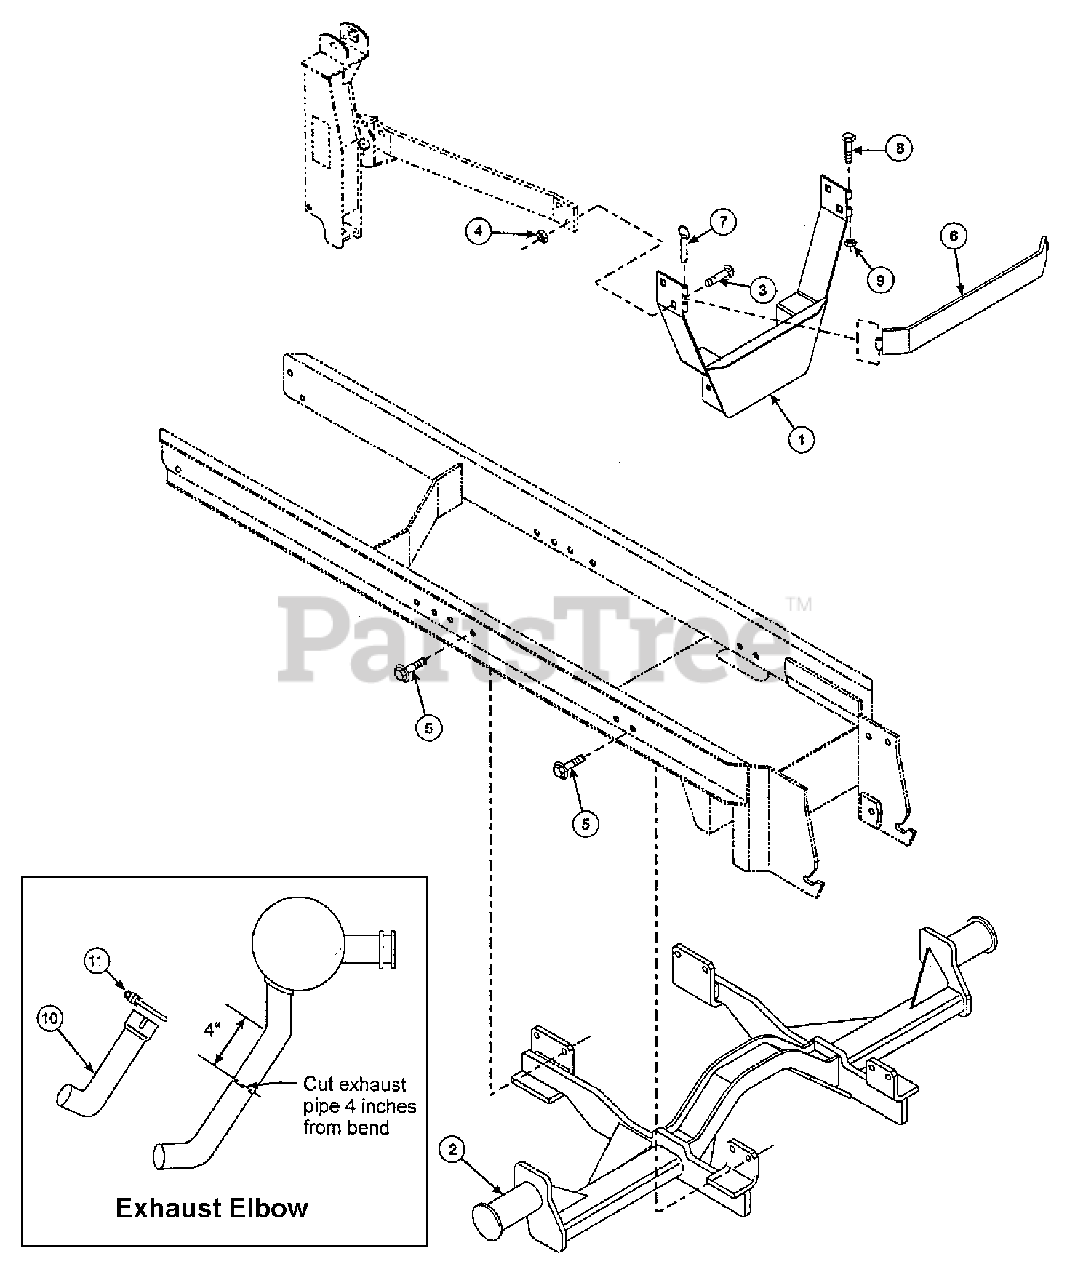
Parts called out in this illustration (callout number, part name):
1	BRACKET, Front Mounting
2	BRACKET, Mid Mounting
3	CARRIAGE BOLT, 1/2-13 x 1-1/2
4	LOCKNUT, 1/2-13
5	CAPSCREW, Hex Flange Head, Whiz Lock, 3/8-16 x 3/4
7	PIN, Locking, 3/8-16 x 4
8	CAPSCREW, Hex Head, 3/8-16 x 4
9	LOCKNUT, Hex, 3/8-16
10	ELBOW, Exhaust
11	CLAMP, Exhaust
